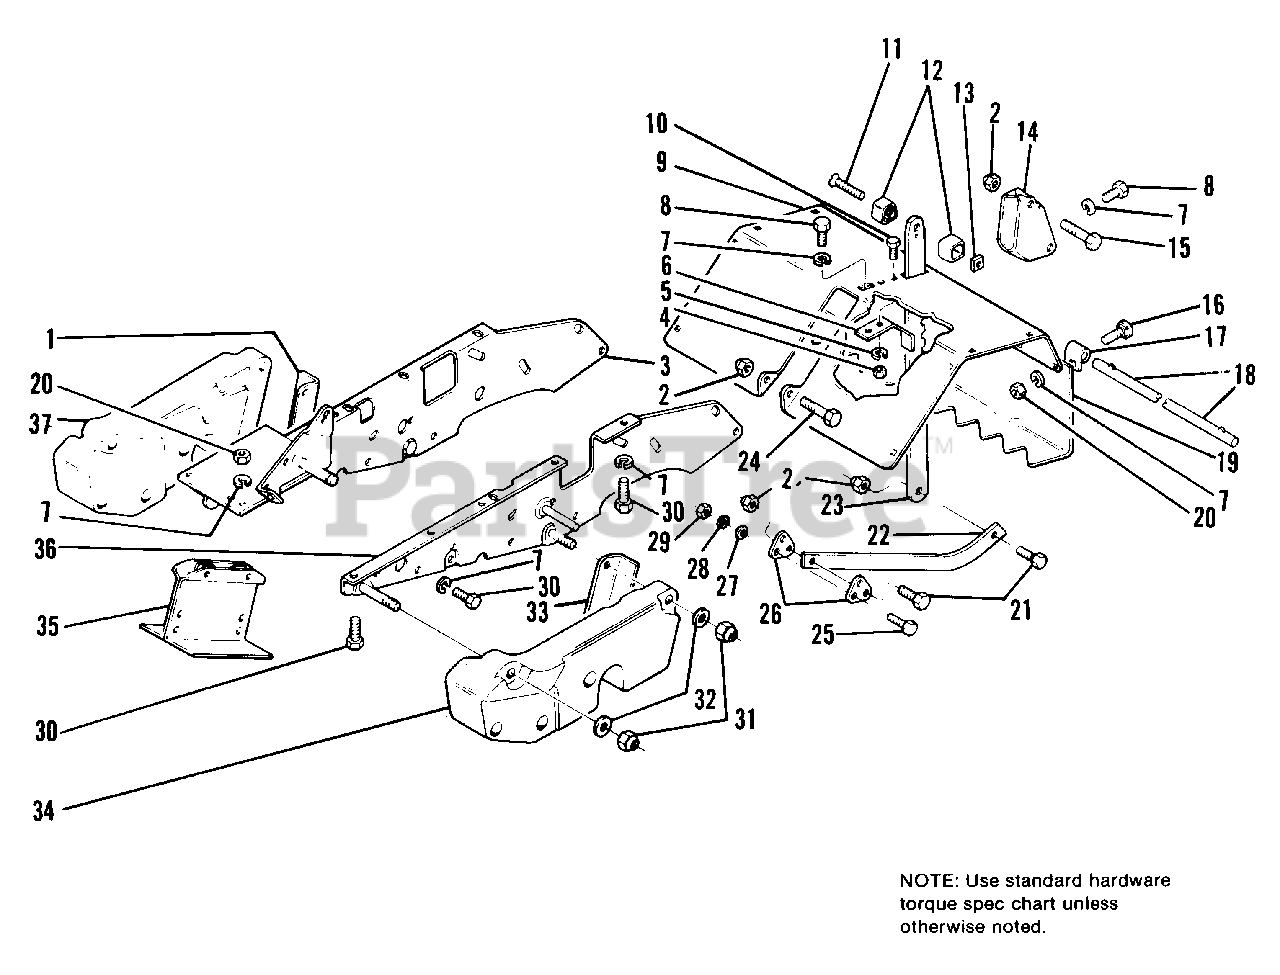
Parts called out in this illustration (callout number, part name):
1	HANGER-Rear R.H.
2	NUT, Hex Cone Lock 5/16-18 Plated
3	FRAME ASSEMBLY-R.H.
4	NUT, Hex 1/4-20 Plated
5	WASHER, Spring Lock 1/4 Plated
6	LEAF SPRING-Depth Control
7	WASHER, Spring Lock 5/16 Plated
8	CAP SCREW, Hex Hd. 5/16-18 x 1/2 Plated, Grade 5
9	TINE SHIELD & DECAL ASSEMBLY
10	CAP SCREW, Hex Hd. 1/4-20 x 1/2 Plated, Grade 5
11	MACHINE SCREW, Slotted Flat Hd. 5/16-18 x 2" Plated
13	NUT, Square 5/16-18 Plated
14	SUPPORT ASSEMBLY
15	CAP SCREW, Hex Hd. 5/16-18 x 2 1/4 Plated, Grade 5
16	BOLT, Carriage 5/16-18 x 3/4 Plated
19	GUARD ASSEMBLY
20	NUT, Hex 5/16-18 Plated
21	CAP SCREW, Hex Hd. 5/16-18 x 1 1/4 Plated, Grade 5
23	DEPTH CONTROL
24	CAP SCREW, Hex Hd. 5/16-18 x 2 1/2 Plated, Grade 5
25	CAP SCREW, Socket Hd. 10-24 x 1" Plated, Grade 5
28	WASHER, Lock External Tooth #10, Plated
29	NUT, Hex #10-24 Plated
30	CAP SCREW, Hex Hd., 5/16-18 x 5/8 Plated, Grade 5
31	NUT, Hex Cone Lock 3/8-16 Plated
32	WASHER, Flat SAE 3/8 Plated
33	HANGER-Rear-L.H.
34	COUNTERWEIGHT-L.H.
35	SUPPORT ASSEMBLY-Counterweight
36	FRAME ASSEMBLY-L.H.
37	COUNTERWEIGHT-R.H.
